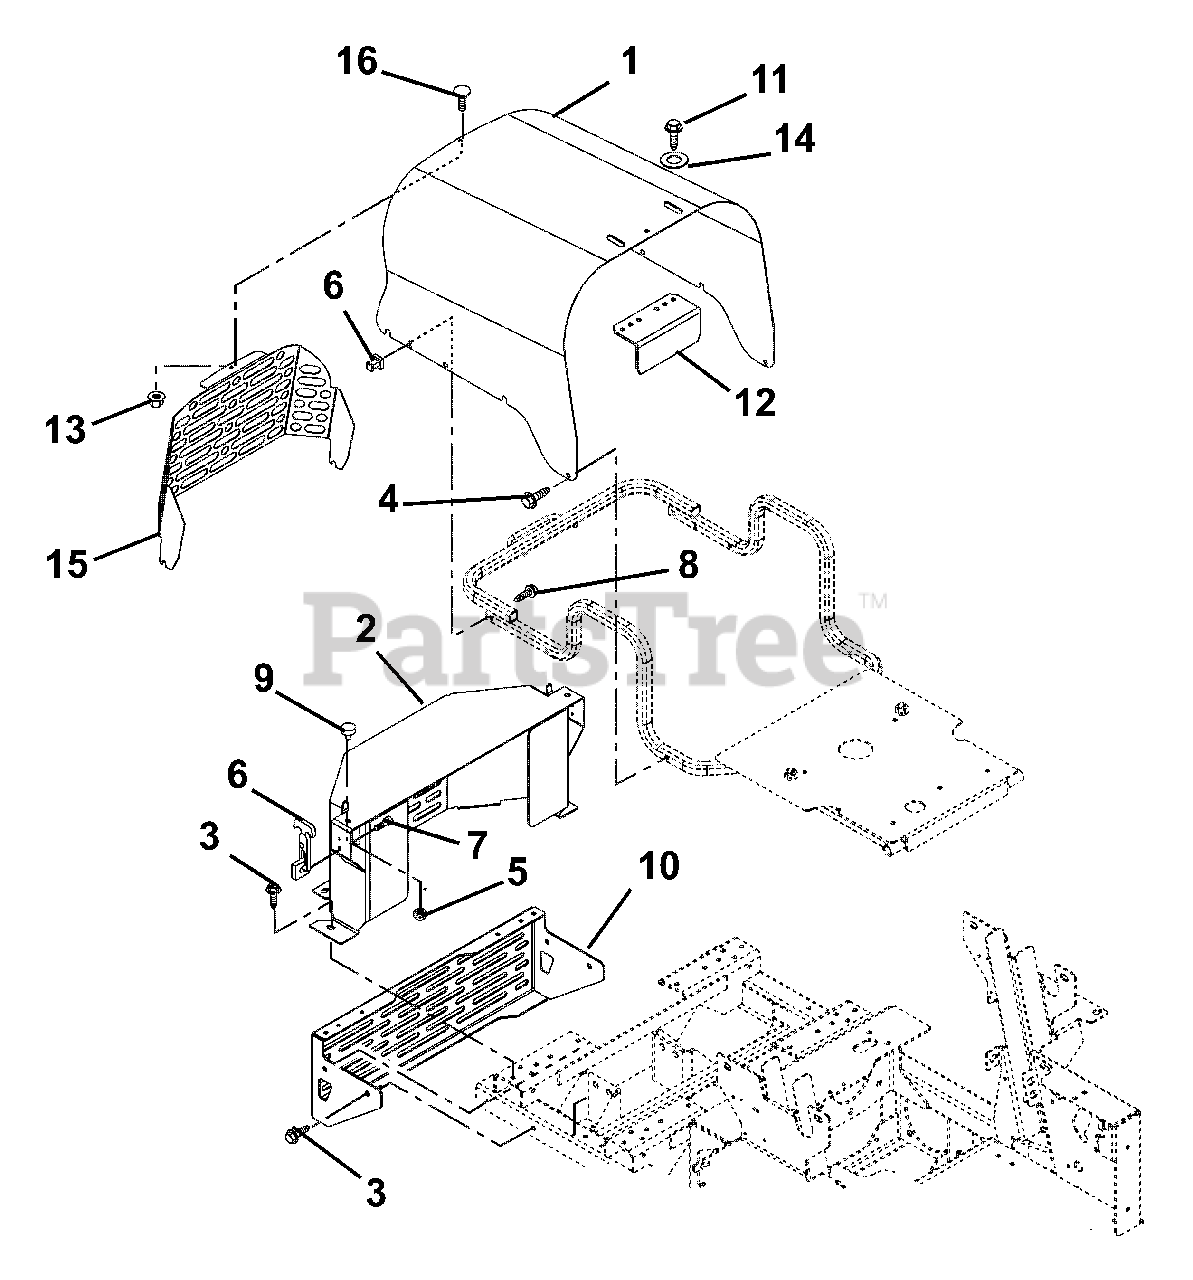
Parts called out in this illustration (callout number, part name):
1	L/C HOOD - RED
2	WMT, BELT GUARD (DIESEL)
3	@SCR-TAP .38-16X.75 HWH TR YWZ
4	@SCR-TAP .38-16X.50 HWH TR YWZ
5	@NUT-SPNLK-FLG .312-18 YWZC
6	LATCH, RUBBER
7	@SCR-MCH 10-24X.50 HWH YWZC
8	@SCR-MCH 10-24X1.50 HWH YWZC
9	BUMPER, RUBBER
10	WMT, BUMPER
11	@SCR-TAP .25-20X.50 HWH TR YWZ
12	GUARD, RADIATOR CAP
13	@NUT-LK-TOP-FLG .25-20 YWZC
14	@WSHR-FL-STL.281X.62X.065 YWZC
15	L/C HOOD GUARD - BLACK
16	@BLT-RDHDSQNK .25-20X.50 G5YZ
